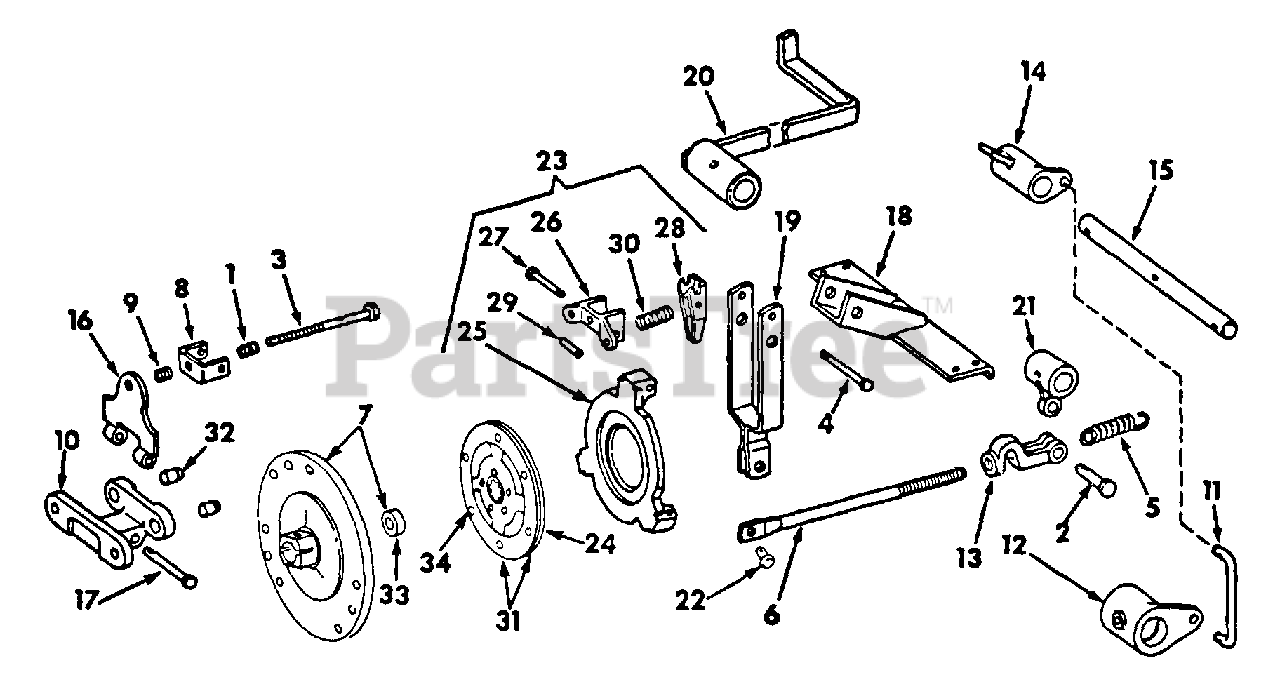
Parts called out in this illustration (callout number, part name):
1	SPRING, CLUTCH BRAKE TEASER
2	PIN, CLUTCH ROD ADJUSTABLE YOKE
3	BOLT, CLUTCH BRAKE
4	PIN, CLUTCH BRAKE YOKE
5	SPRING, CLUTCH RETURN
6	ROD, CLUTCH OPERATING
7	PLATE ASSY, PRESSURE
8	YOKE, CLUTCH BRAKE
9	SPRING, CLUTCH BRAKE STABILIZER
10	RETAINER, CLUTCH BRAKE
11	ROD, CLUTCH LINKAGE
12	LEVER, CLUTCH PEDAL
13	YOKE CLUTCH ROD ADJUSTING
14	LEVER, CLUTCH & SAFETY STARTING SWITCH
16	ARM ASSY, BRAKE
18	BRACKET ASSY, CLUTCH RELEASE
19	YOKE ASSY, CLUTCH RELEASE
20	PEDAL ASSY CLUTCH REPLACES, 404 659 R1
21	LEVER, CLUTCH
22	PIN, CLUTCH ROD, END
23	PLATE ASSY, CLUTCH PRESSURE
24	DISC W/FACINGS ASSY, CLUTCH DRIVEN
25	PLATE, PRESSURE
26	BRACKET, LEVER
27	PIN, LEVER PIVOT
28	LEVER, RELEASE
29	PIN, PRESSURE PLATE
30	SPRING, PRESSURE
31	PACKAGE, CLUTCH FACING
32	LINING ASSY, BRAKE
33	BUSHING, PRESSURE PLATE
34	RIVET, CLUTCH FACING
